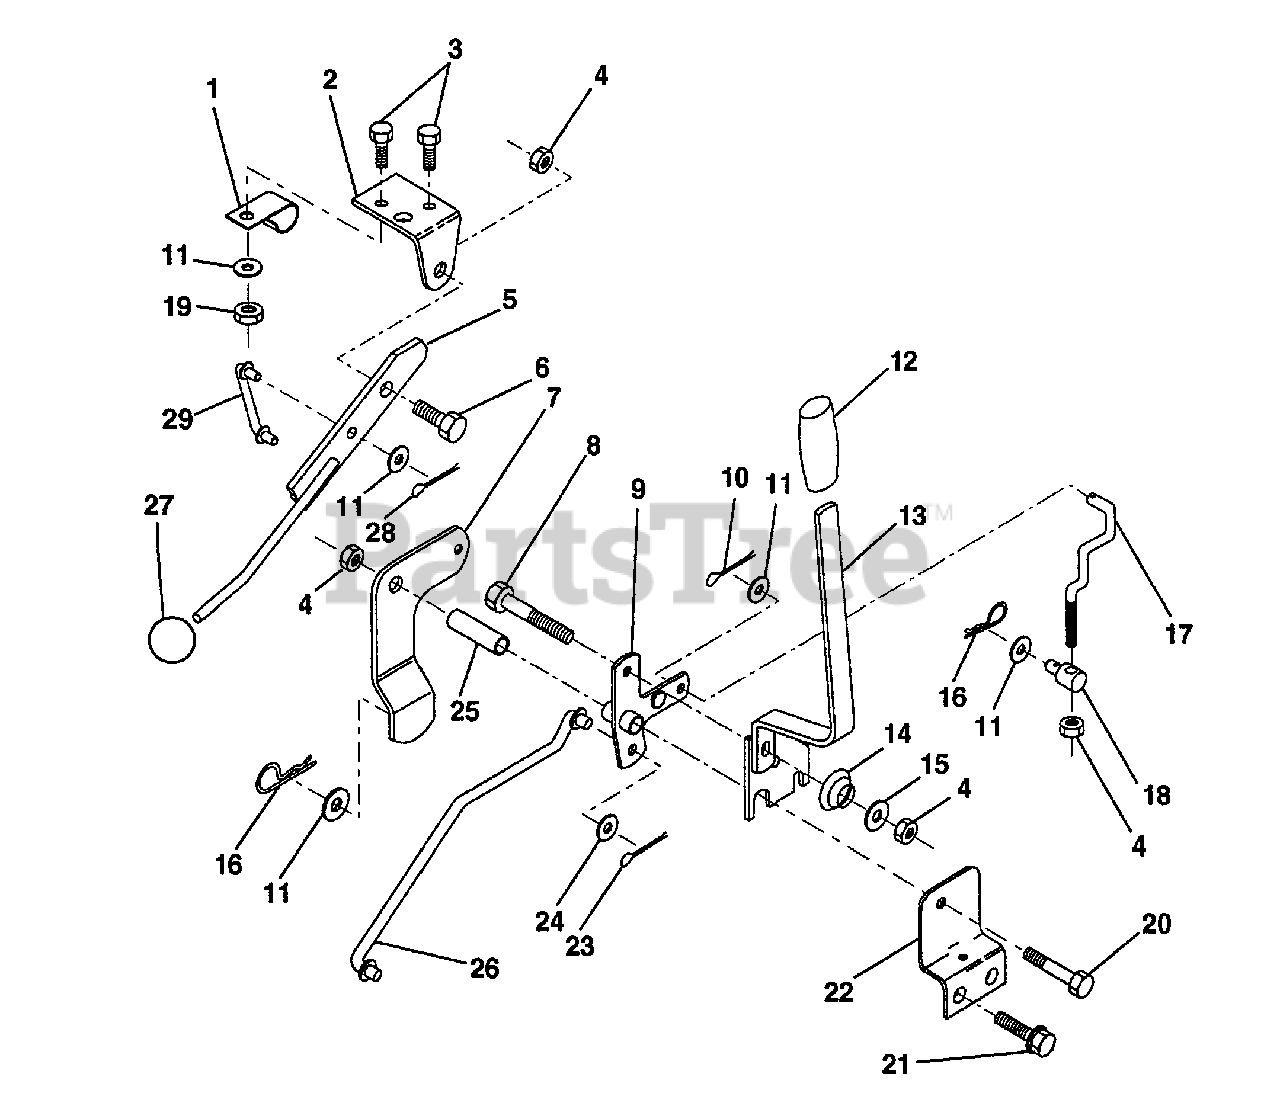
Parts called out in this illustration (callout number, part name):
1	Clip, Insulated
2	Bracket, Mower Clutch
3	Bolt, Fin Hex 1/4-20 UNC x 1/2 Gr. 5
4	Nut, Crownlock 3/8-16 UNC
5	Assembly, Clutch Lever
6	Bolt, Shoulder
7	Assembly, Mower Clutch Arm
8	Bolt, Hex 3/8-16 UNC x 2-1/4
9	Assembly, Bracket Lift
10	Pin, Cotter 1/8 x 3/4
11	Washer 13/32 x 13/16 x 16 Ga.
12	Grip, Handle
13	Assembly, Lift Handle
14	Spring, Compression
15	Washer 13132 x 34 x 12 Ga.
16	Retainer, Spring
17	Link, Front Lift
18	Trunnion, Threaded 3/8-16
19	Nut, Crownlock 1/4-20
20	Bolt, Fin Hex 3/8-16 UNC x 2-3/4
21	Screw, Hex Thdrol. 5/16-18 x 1/2
22	Bracket, Mower Height
23	Pin, Cotter 1/8 x 1
24	Washer 17/32 x 1 x 16 Ga.
25	Tube, Spacer
26	Rod, Mower Lift
28	Pin, Cotter 3/32 x 3/4
29	Link, Mower Clutch
